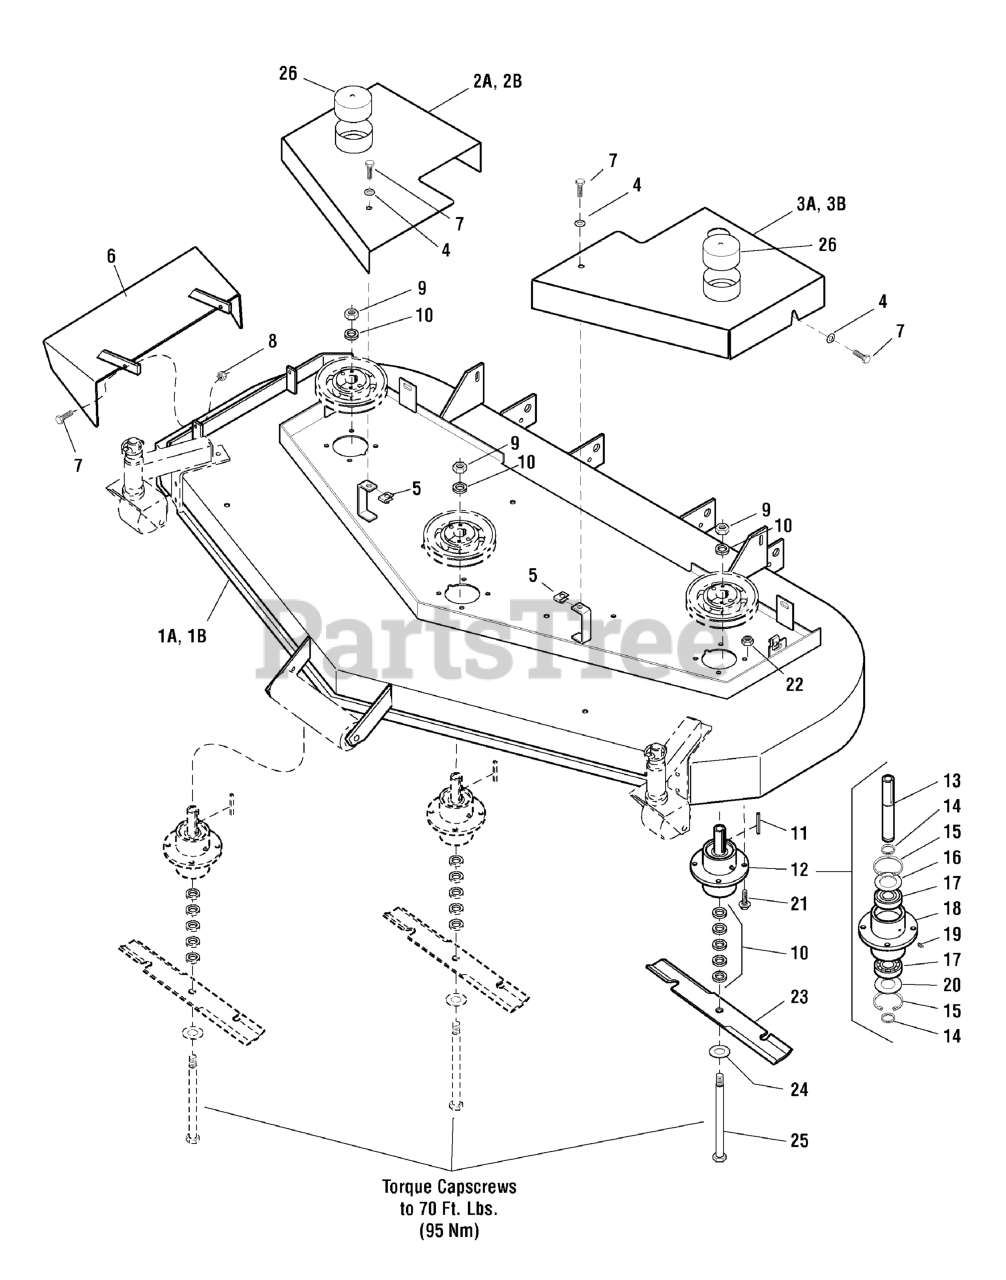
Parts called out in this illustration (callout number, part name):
1A	DECK SHELL W/DECALS, 72" (see footnote)
1B	DECK SHELL W/DECALS, 72"
2A	SPINDLE COVER-RH
2B	DECK SHIELD - RH
3A	SPINDLE COVER-LH
3B	DECK SHIELD - LH
4	WASHER, 5/16" SAE
5	BODY CLIP, 5/16-18-7GA MATERIAL
6	DISCHARGE CHUTE
7	BOLT, 5/16-18 X 1 GD5 YZ
8	NUT, 5/16-18 Hex Nylon Lock
9	NUT, 5/8-11 Hex
10	SPACER, .63 x 1.06 x .23
11	KEY, 1/4 SQ. X 2-1/2
12	SPINDLE ASSEMBLY, Complete
13	SPINDLE SHAFT
14	SNAP RING, External
15	SNAP RING, Internal
16	SPINDLE WASHER, Top
17	BEARING
18	SPINDLE HOUSING
19	GREASE FITTING
20	SPINDLE WASHER, Bottom
21	BOLT, Flange Head, 5/16-18 x 1-1/2
22	NUT, 5/16-18 Hex Nylon Lock
23	BLADE, 25" (SET OF THREE)
24	WASHER, 5/8" GRADE 8, YZ
25	BOLT, 5/8-11 x 9-1/2
26	VINYL CAP
